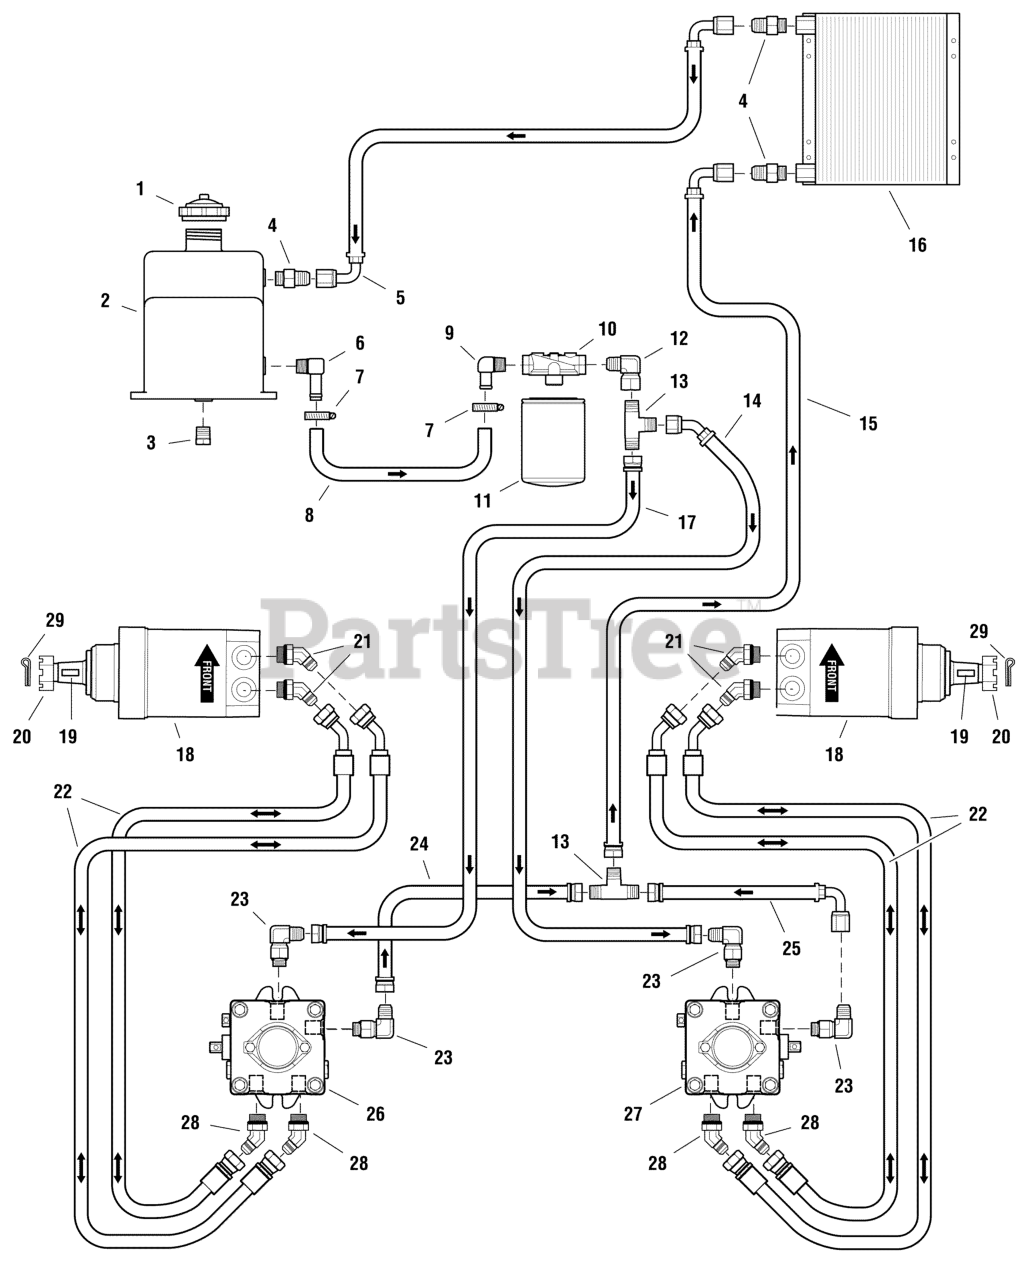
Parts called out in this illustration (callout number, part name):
1	CAP, Reservoir
2	HYDRAULIC OIL RESERVOIR
3	PLUG, 1/2" NPT
4	FITTING, NPT - JIC #8
5	HOSE ASSEMBLY, 51"
6	FITTING, 1/2" NPT, 90 Deg.
7	CLAMP, #10 Hose
8	HOSE, 5/8 Push-lock, 13.00"
9	FITTING, 1/2" NPT, 90 Deg.
10	FILTER HEAD
11	FILTER, HYDRAULIC, SERVICE PART (PKG)
12	FITTING, NPT - JIC #8 Female, 90 Deg.
13	FITTING, TEE, JIC #8
14	HOSE ASSEMBLY, 28"
15	HOSE ASSEMBLY, 79"
16	OIL COOLER
17	HOSE ASSEMBLY, 42"
18	HYDRAULIC WHEEL MOTOR, Complete
19	KEY
20	NUT, CASTLE, 1-20
21	FITTING, O-Ring, 45 Deg.
22	HOSE ASSEMBLY, (23), HP, ST X 45
23	FITTING, O-Ring, 90 Deg.
24	HOSE ASSEMBLY, 15"
25	HOSE ASSEMBLY, 7"
26	HYDRAULIC PUMP - LH
27	HYDRAULIC PUMP - RH
28	FITTING, O-Ring, 45 Deg.
29	PIN, COTTER, 1/8" X 2"
30	WIRE LOOM, 1/2" ID, 40" LONG
